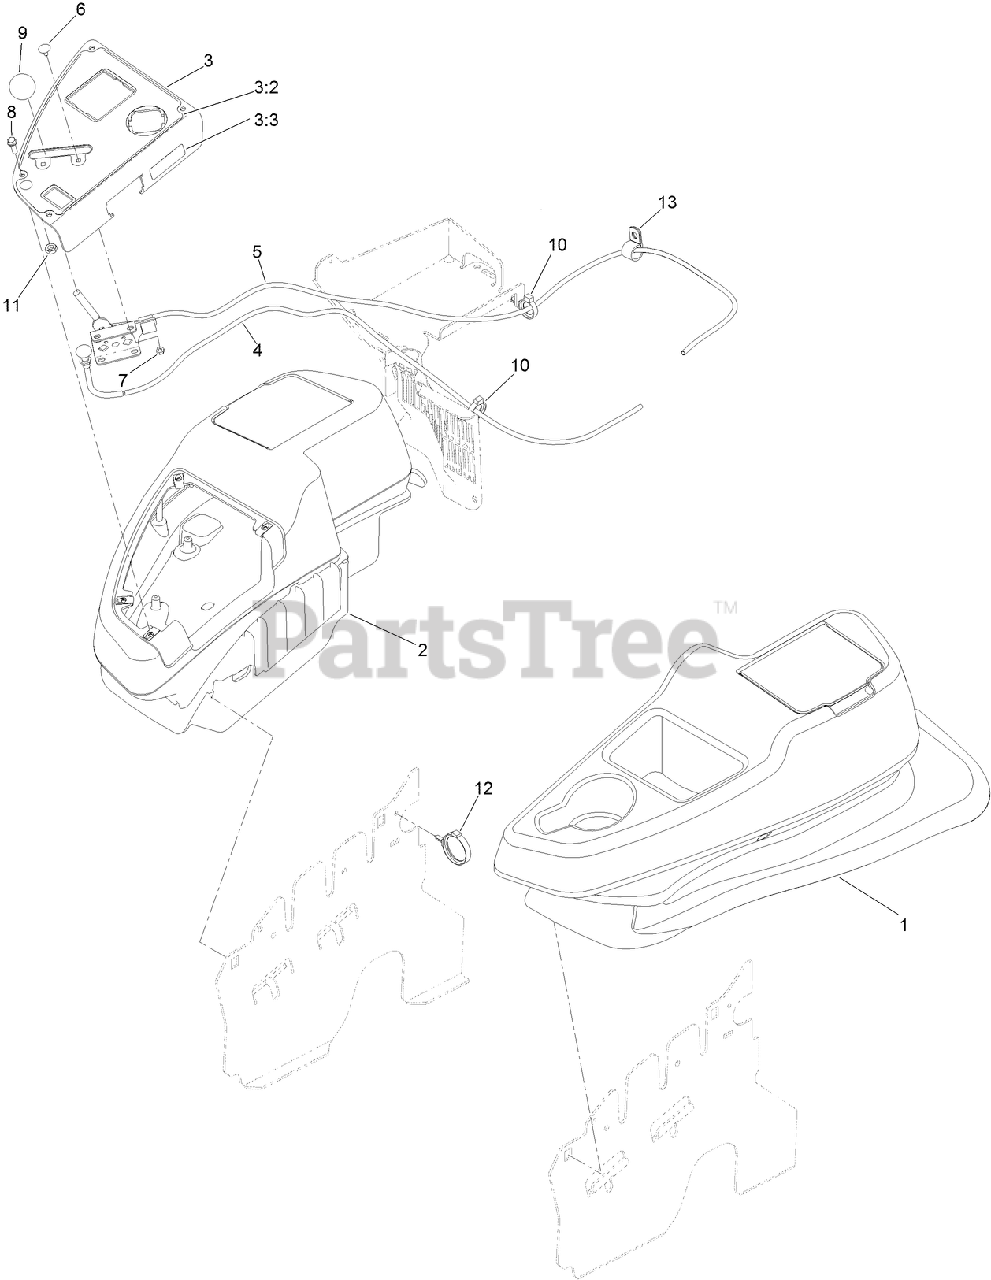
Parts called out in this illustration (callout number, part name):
1	LH CONSOLE ASM
2	RH CONSOLE ASM
3	CONTROL PANEL ASM
3:2	DECAL-PANEL, CONTROL
3:3	DECAL-FUSES
4	CONTROL-CHOKE
5	THROTTLE-CONTROL
6	BOLT-CARR
7	NUT-LOCK, NI
8	SCREW-HWH
9	KNOB-BALL
10	CLAMP-HOSE
11	NUT-HJ
12	CLAMP-HARNESS
13	CLIP-LOOM
